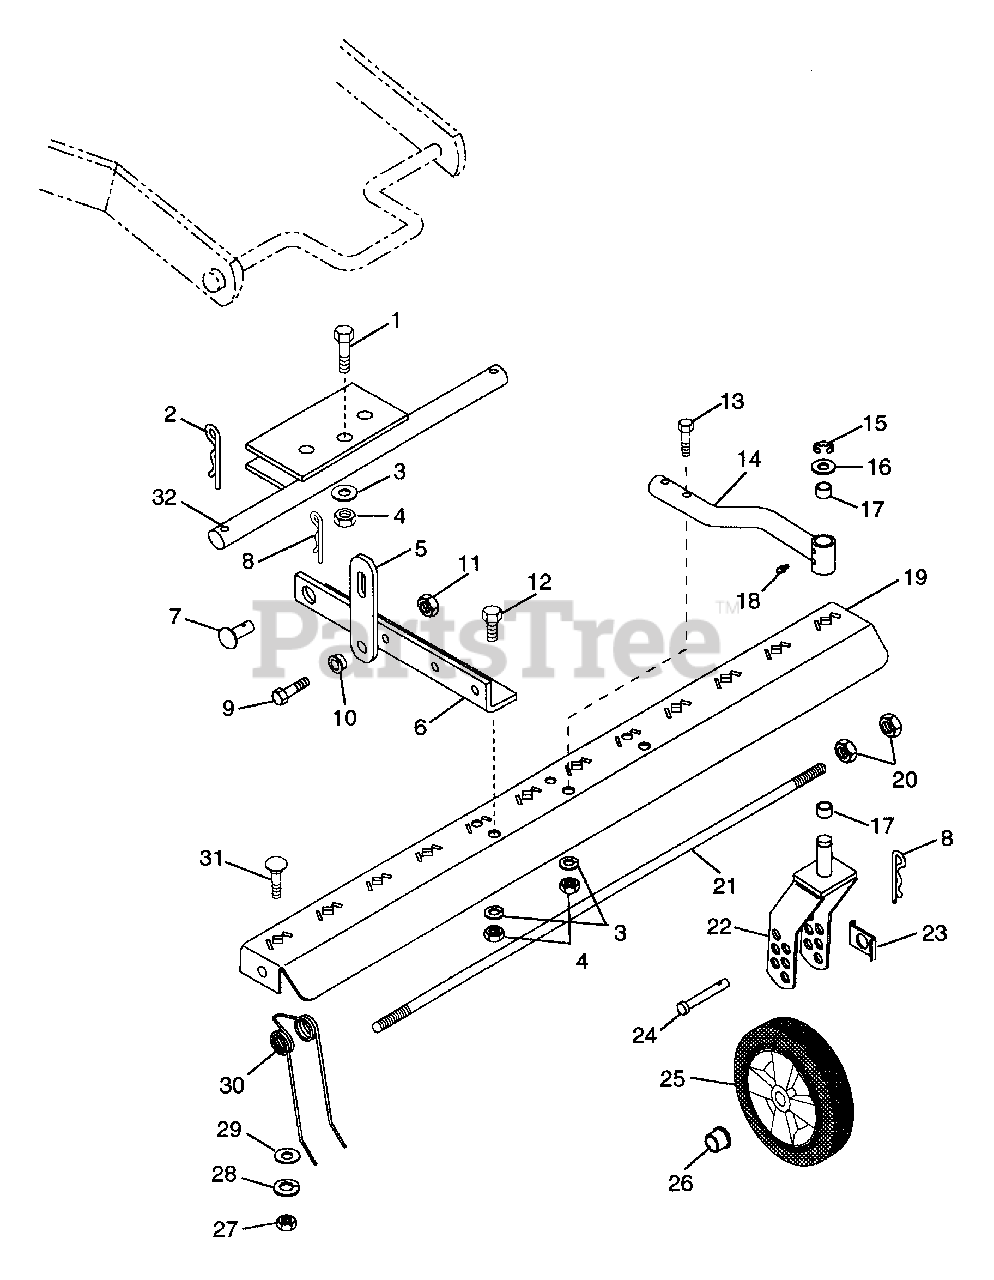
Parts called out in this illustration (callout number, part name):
1	BLT-HEX .38-16X1.50 PL GR2
2	PIN-HAIR INT .09X.188 PL
3	WSHR-LK .375X.115 HVY PL
4	NUT-HEX .375-16
5	LIMITING ARM
6	ANGLE BRACKET
7	PIN-CLEV .50X1.25 RH ST PL
8	PIN-HAIR INT .14X.4X2.75
9	BLT-HEX .31-18X1.25 PL GR2
10	BSHG-FLG .344X.468X.485X.750
11	NUT-LK .312-18 GR A PL
12	BLT-HEX .38-16X1.00 PL
13	BLT-HEX .38-16X1.75 PL GR2
14	WHEEL BRACKET WELDMENT
15	RG-RTNG-EXT .438X.035
16	WSHR-FL-STL .505X.880X.072 PL
17	BSHG-SLV .500X.625X.500
18	FTG-LUBE .25-28X.256 YWZC
19	CHANNEL
20	NUT-LK-FLG .250-20 PL
22	WHEEL YOKE WELDMENT
23	AXLE TAB
24	PIN-CLEV .494X2.62 YWZC
25	WHEEL
26	BSHG-FLG .500X.625X.500X.750
27	NUT-HEX .312-18
28	WSHR-LK .312X.097 PL HVY
29	WSHR-FL-STL .328X1.0X.094 PL
31	BLT-RDHDSQNK .31-18X.75 SHT PL
32	BRACKET WELDMENT
